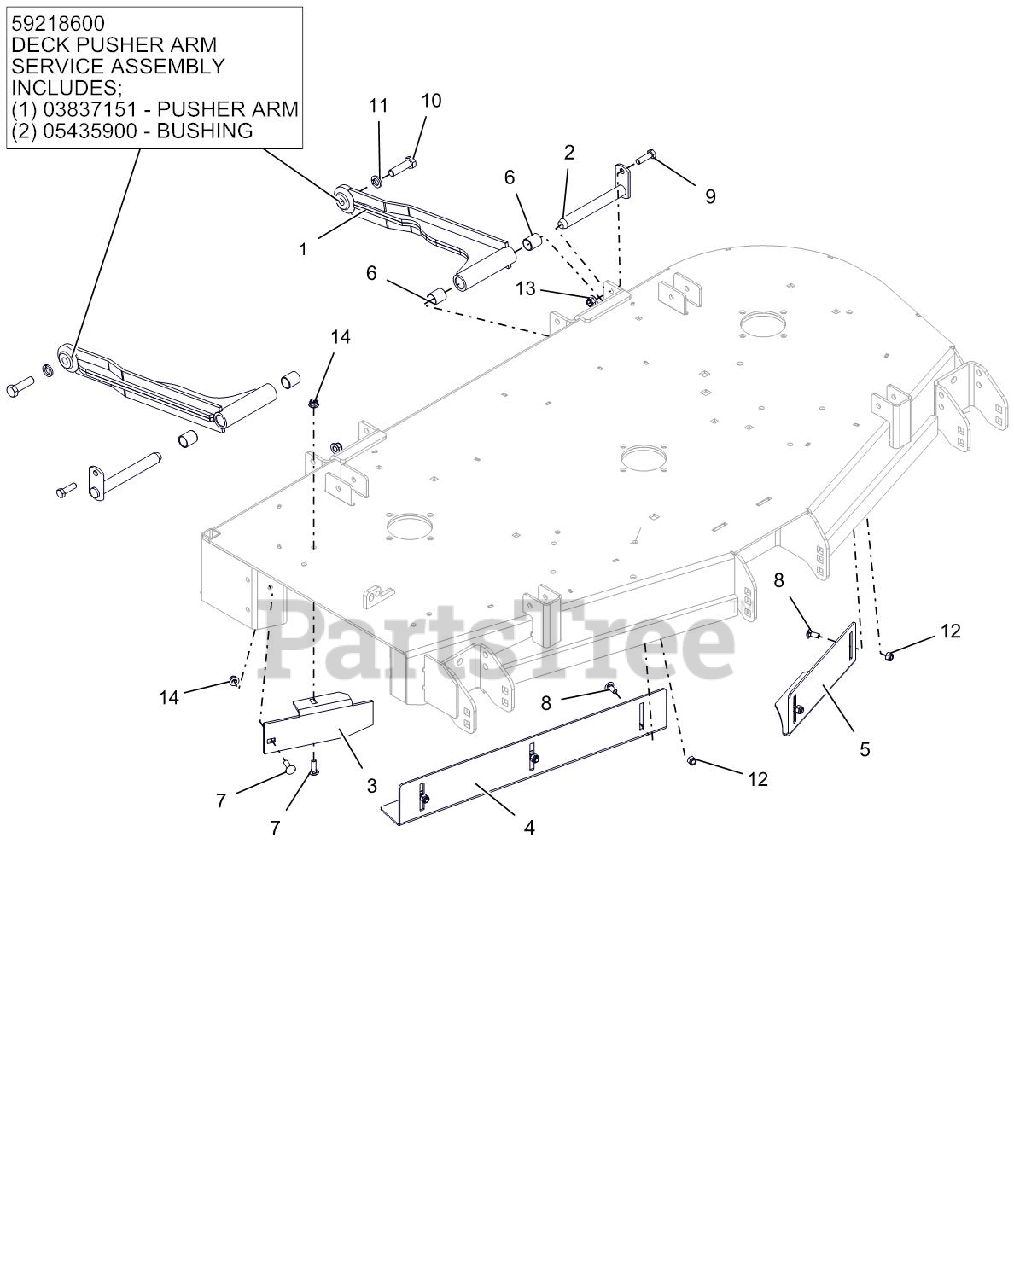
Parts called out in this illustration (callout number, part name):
1	BRG, .750 X .875 X 1.000
1	DECK STABILIZER ARM W/BUSHINGS
1	DECK STABILIZER ARM - BLACK
2	WELDMENT, MOWER MTG. PIN
3	52" DISCHARGE BAFFLE - RED
4	52" RH VACUUM BAFFLE - BLK
5	52" LH VACUUM BAFFLE - BLK
6	BRG, .750 X .875 X 1.000
7	@BLT-RDHDSQNK .31-18X1.00 G5YZ
8	@BLT-RDHDSQNK .31-18X.75 G5YZ
9	@BLT-HEX .38-16X1.25 GR5 YWZC
10	BLT-HEX .50-13X1.75 GR5EP80 YZ
11	@WSHR-LK .50X.125 REG YWZC
12	@NUT-LK-NYL .312-18 YWZC
13	@NUT-LK-NYL-FLG .38-16 YWZC
14	@NUT-LK-NYL-FLG .31-18 YWZC
